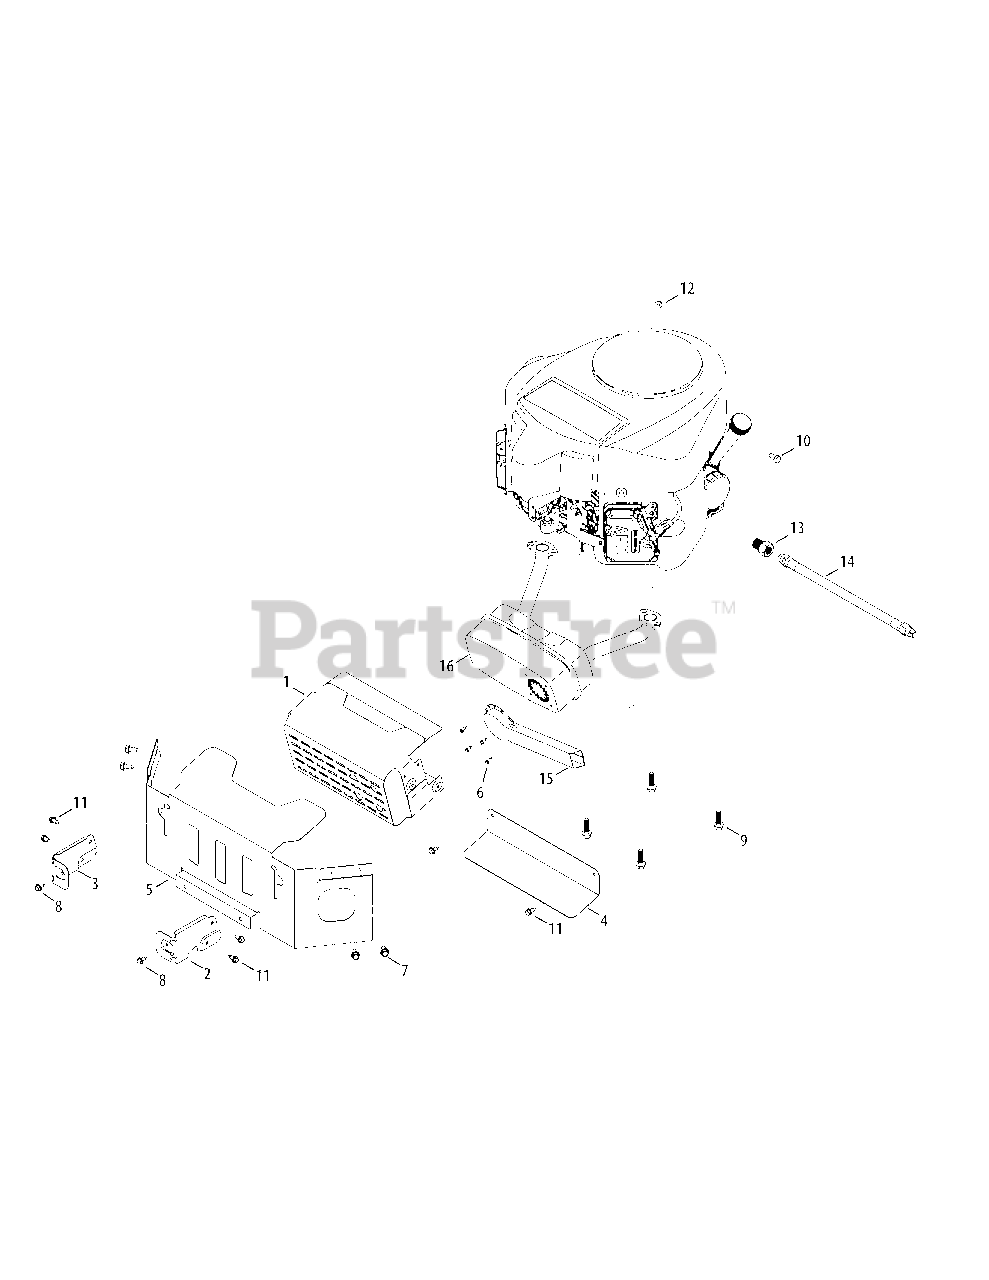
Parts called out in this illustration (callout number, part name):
1	Muffler Shield Assembly
2	Muffler Shield Bracket, RH
3	Muffler Shield Bracket, LH
4	Lower Heat Shield
5	Muffler Shield
6	Hex Washer Screw, #8-18 x .500
7	Hex Washer Screw, 5/16-18 x .750
8	Screw, 1/4-20 x .375
9	Screw, 3/8-16 x 1.25
10	Hex Cap Screw, M8-1.25 x 16
11	Hex Washer Screw, 1/4-20 x .625
12	Flange Lock Nut, 1/4-20
13	Fitting, 1.0 Hex x M20
14	Oil Drain Hose
15	Muffler Deflector Long
16	Twin Muffler
